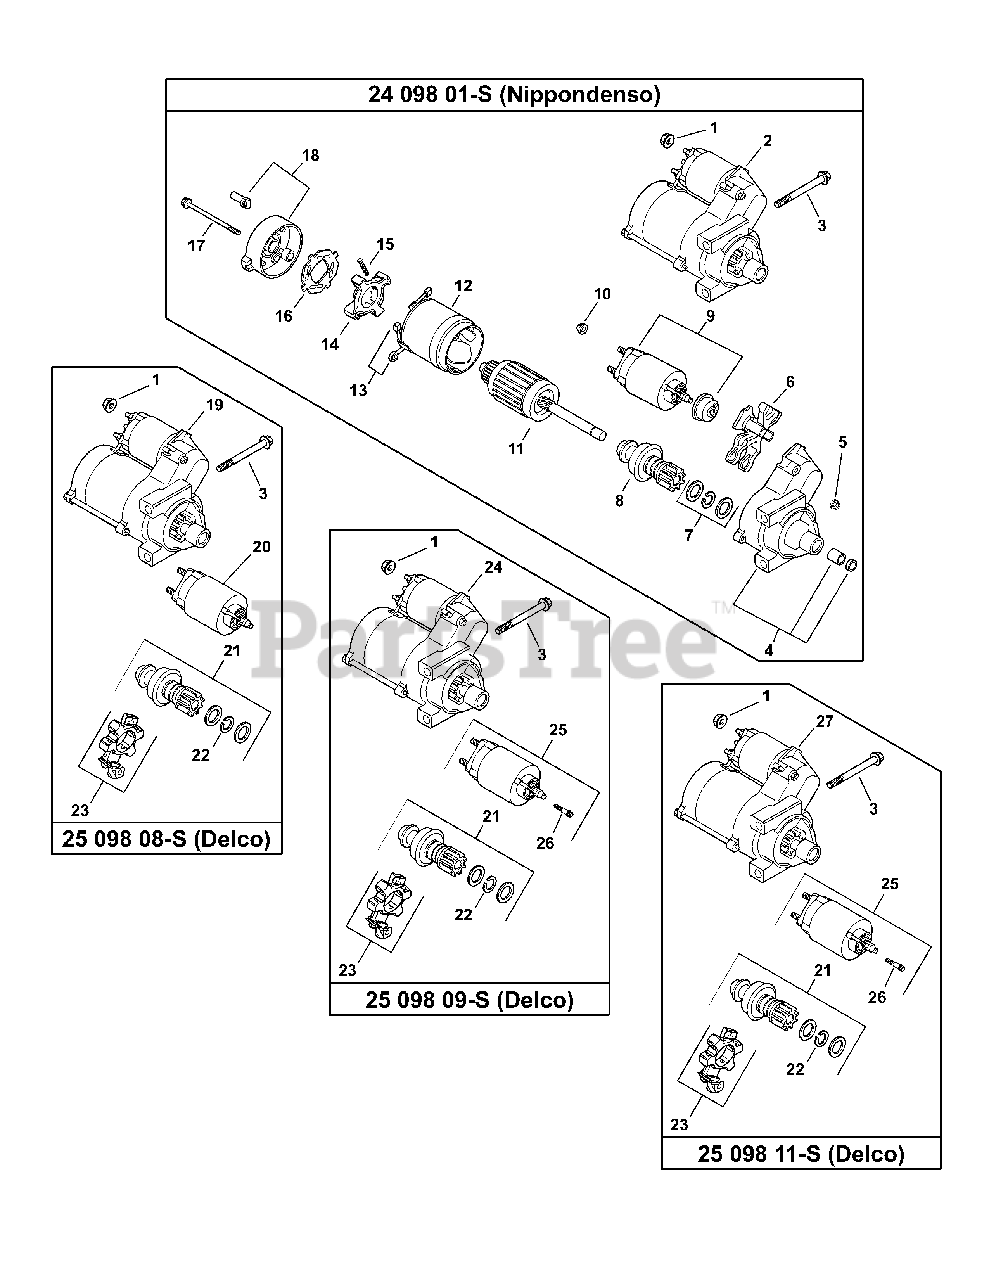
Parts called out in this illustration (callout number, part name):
1	Nut, Flg M8X1.25
2	Starter Assy, Solenoid Shift
3	Screw, Flg M8x1.25x80
4	Drive, End Cap
5	Nut, Starter
6	Lever, Starter Drive
7	Kit, Starter Repair
8	Drive Pinion
12	Frame w/ Brushes
13	Brush Holder
14	Brush & Spring Kit
15	Spring, Brush
18	Commutator, End Cap
19	Starter Assy, Solenoid Shift
20	Solenoid
21	Kit, Starter Pinion (Includes 22)
22	Ring, Retaining
23	Kit, Brush Holder
24	Starter Assy, Solenoid Shift
25	Kit, Solenoid (Includes 26)
26	Screw, External Torx Head M4x0.7x26
27	Starter Assy, Solenoid Shift
